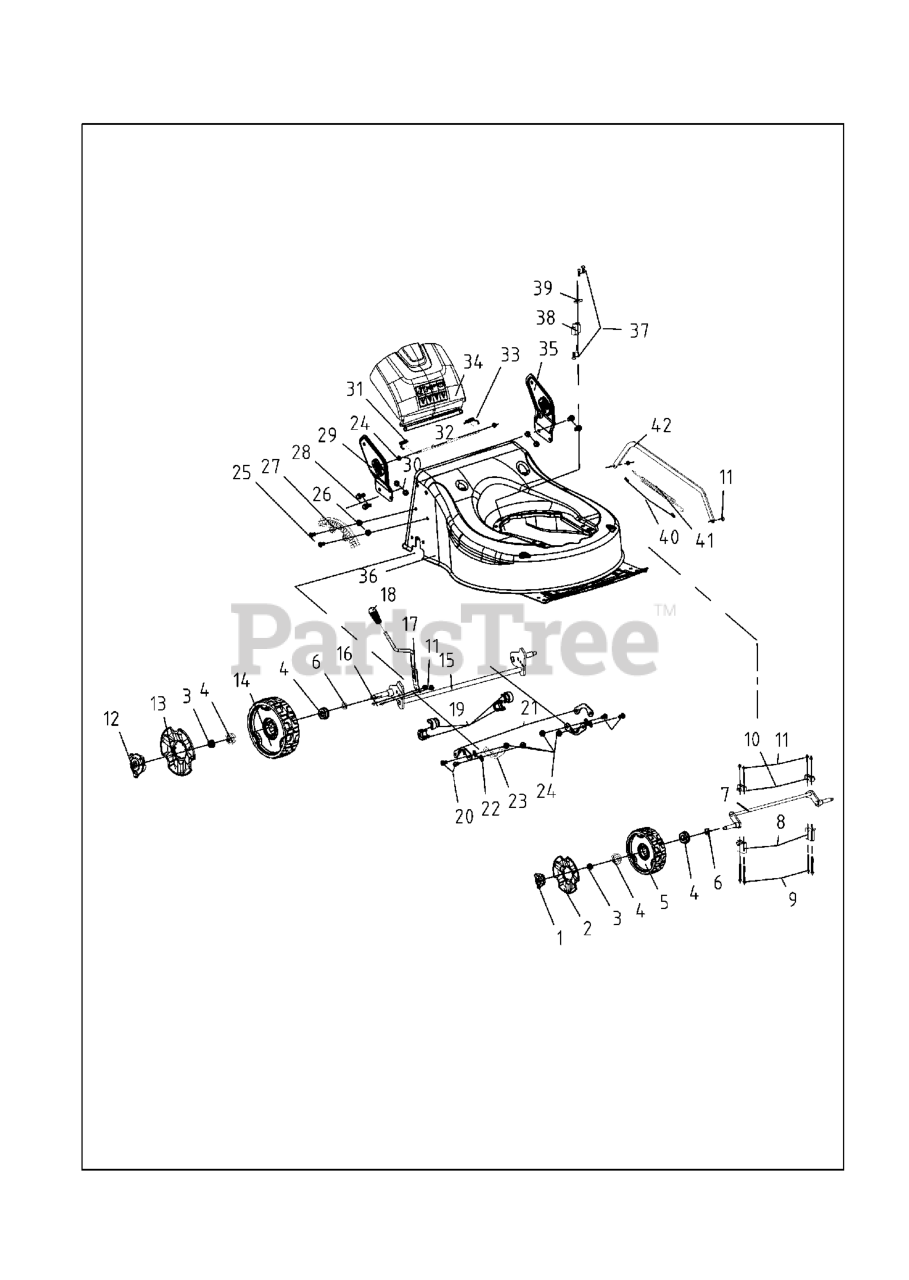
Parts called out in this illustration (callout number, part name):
1	WHEEL COVER 6" #25340700101
2	COVER 7 WHEEL COVER
3	LOCKING BOLT M8,GB6187.1 #2680
5	WHEEL ASSY 7 WHEEL
6	WASHER Ï?12 #26800706202
7	FRONT AXLE ASSY
11	LOCKING BOLT M6,GB889.1 #26800
12	WHEEL COVER 8" #25341000101
13	WHEEL COVER 8" #25341100101
14	WHEEL #25341300101
15	REAR AXLE ASSY
16	WASHER M6*14 #26800203001
17	HANDLE ASSY
18	KNOB HEIGHT ADJUSTMENT #25341
19	COVER AXLE #25235300101
20	SCREW M6*16 #26800204601
21	FIXING PLATE #26300314601
22	O-RING #25100175201
23	FIXING PLATE #26300124401
24	LOCK NUT M6,GB/T6187.1-2000 #2
27	SEGMENT #25214200102
28	BOLT M8*16 #26800606401
29	BRACKET RH
31	SPRING #26801125501
33	BRACKET #26801125401
40	TUBING #29000300101
41	SPRING #26801103903
42	CONNECTING ROD
